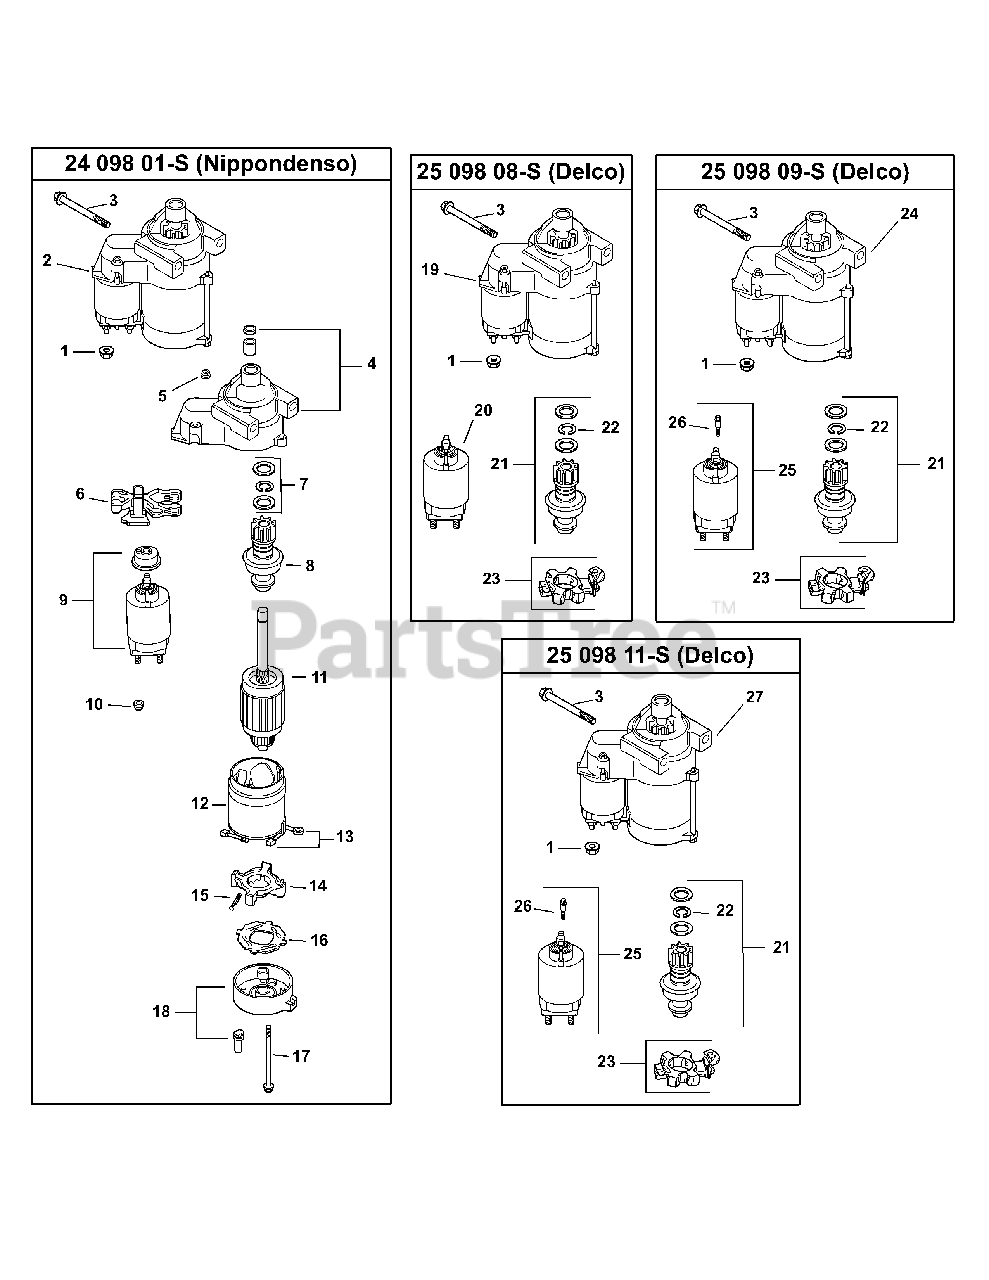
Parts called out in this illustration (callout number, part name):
1	Nut, Flg M8X1.25
2	Starter Assy, Solenoid Shift
3	Screw, Flg M8x1.25x80
4	Drive, End Cap
6	Lever, Drive
7	Kit, Starter Repair
8	Drive Pinion
12	Frame w/ Brushes
13	Brush Holder
14	Brush & Spring Kit
15	Spring, Brush
18	Commutator, End Cap
19	Starter Assy, Solenoid Shift
21	Kit, Starter Pinion (Includes 22)
22	Ring, Retaining
23	Kit, Brush Holder
24	Starter Assy, Solenoid Shift
25	Kit, Solenoid (Includes 26)
26	Screw, External Torx Head
27	Starter Assy, Solenoid Shift
